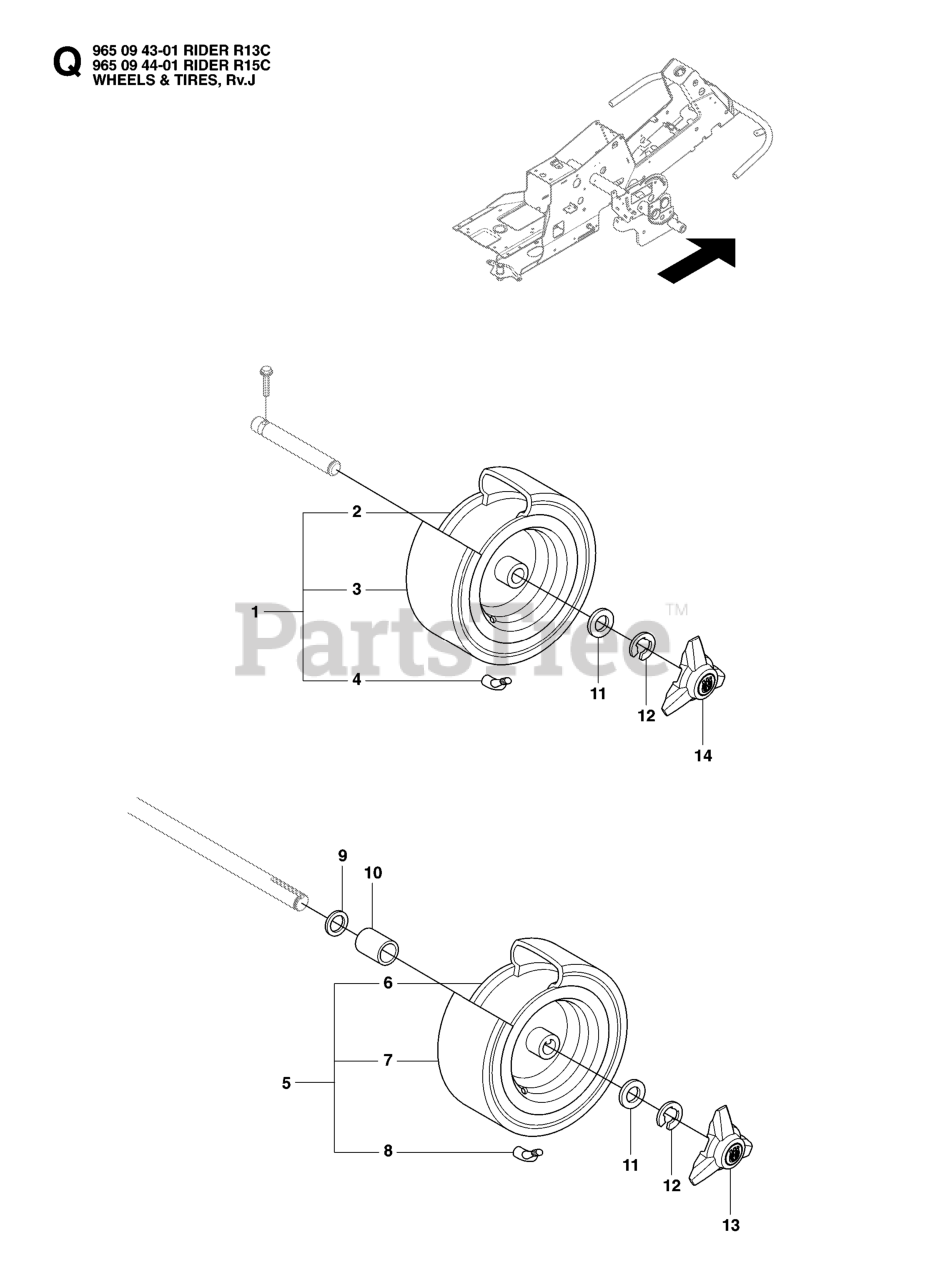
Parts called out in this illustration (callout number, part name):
5	WHEEL
6	RP RIM
10	SPACE SLEEVE
12	RETAINING RING
